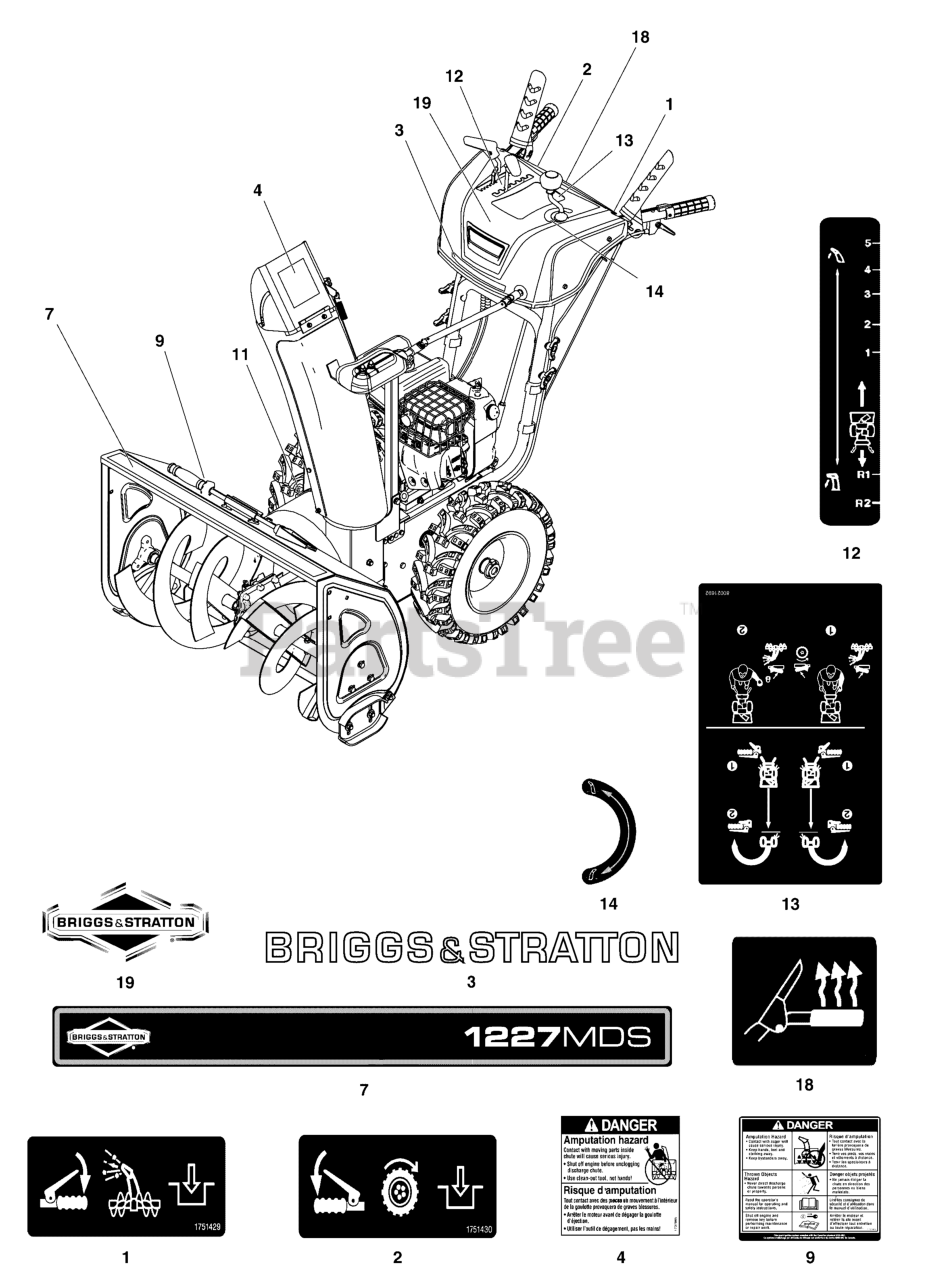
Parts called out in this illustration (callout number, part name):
1	DECAL, Auger Control
2	DECAL, Traction Control
3	DECAL, Briggs & Stratton Wordmark
4	DECAL, Danger Chute Warning, FR/ENG
7	DECAL, Model 1227MDS
9	DECAL, Danger Foot, FR/ENG
11	DECAL, I.D. Plate
12	DECAL, 1-6 Transmission Speed Control
13	DECAL, Free Hand Operation
14	DECAL, Chute Rotation
18	DECAL, Heated Hand Grip Switch
19	DECAL, Briggs & Stratton Logo
